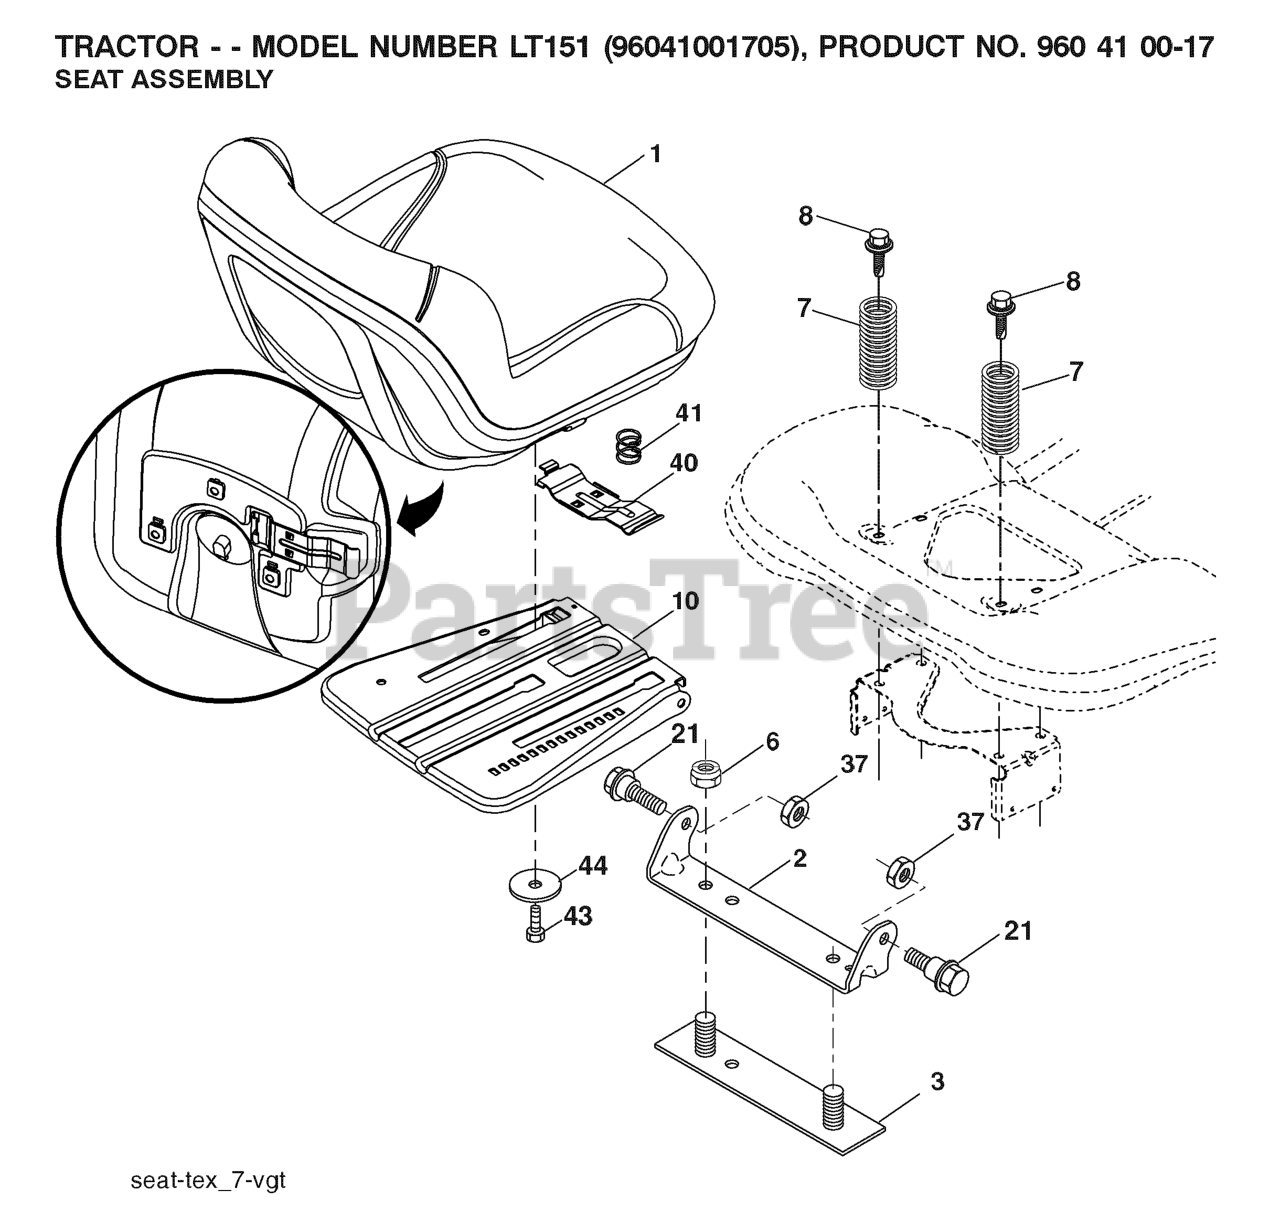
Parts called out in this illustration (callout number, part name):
1	SEAT.TH130.GRY.MILSCO.
2	BRKT.PIVOT.FENDER
3	STRAP
6	NUT
7	SPRING COMPRESSION
8	BOLT.5/16-18UNCX3/4 W/SEMS.BLK
10	PAN.ASM.SEAT.3PT
21	BOLT.SHOULDER.5/16-18
37	NUT.71038.31-18.HEX.NYLOCK
40	HANDLE.SLIDE.SEAT.TEX.BLACK
41	SPRING.LATCH.SEAT.TEX
44	WASHER 13/32 X 2-3/8 X 12GA
